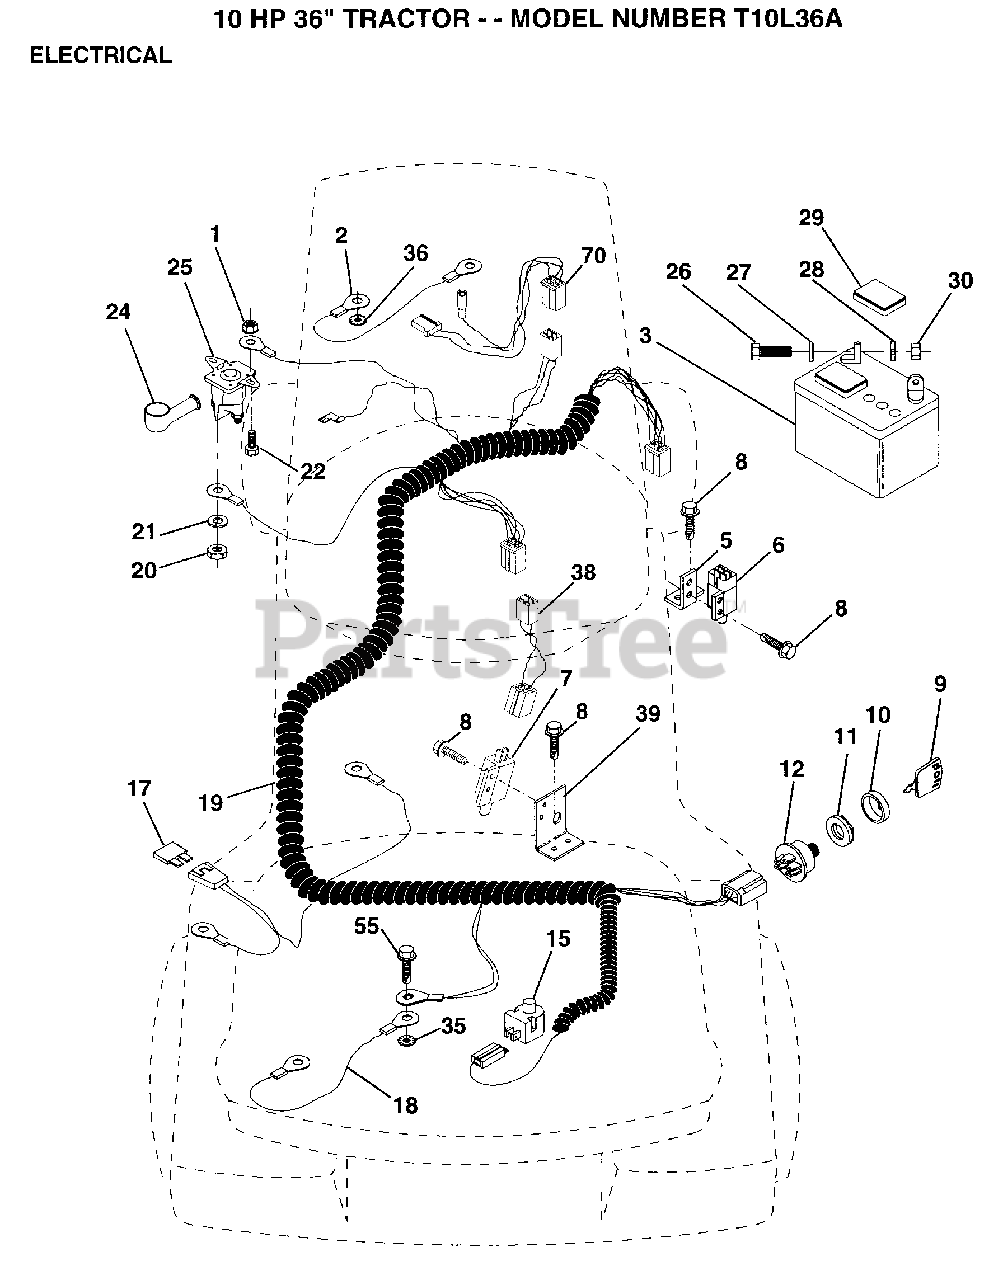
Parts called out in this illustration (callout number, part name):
1	NUT
2	CABLE ASM.
5	BRACKET LT
6	SWITCH INTERLOCKT
7	SWITCH-INTER. GT
8	SCREW
9	KEY STEEL DELTA
10	COVER KEY SWITCH
14	WIRE TIE
15	SWITCH SEAT
17	FUSE HYT
18	CABLE ASSY
19	HARNESS IGNITION
20	NUT
22	BOLT
26	BOLT LT
27	WASHER
28	LOCKWASHER
29	"CAP,BATTERY "
35	LOCKWASHER.5/16.E
36	LOCKWASHER
38	ADAPTER.HARN.SERV
39	BRACKET SWT CLUTC
55	SCREW LT
70	HARNESS ENG DUAL
